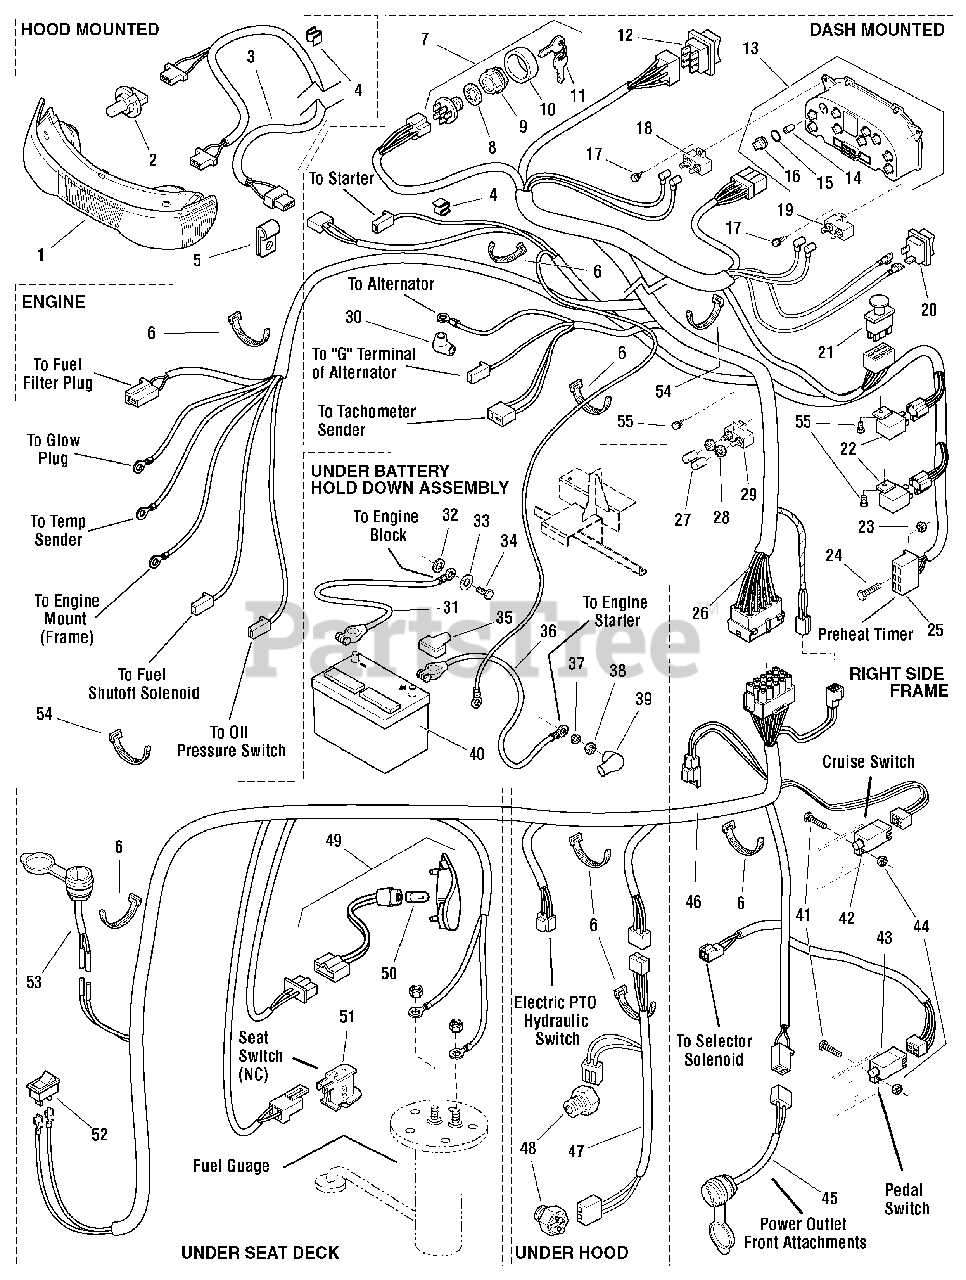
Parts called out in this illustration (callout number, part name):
2	BULB, Headlight, Halogen
3	HARNESS, Headlight
5	CLAMP, Wire 3/8 Diameter
6	TIE, Self Locking 7 in. Long
7	SWITCH ASSEMBLY, Ignition 5/8-32, 6 Pin INDAK
8	LOCKWASHER, Internal Tooth, 5/8, Thin
9	NUT, Hex Flange 5/8-32 Ignition Switch
10	COVER, Ignition Switch, Black
11	KEYS, Set of 2
12	SWITCH, Electric Lift, 6 Terminal
13	PANEL, Instrument
14	BULB, Instrument Panel
15	SEAL, Lamp Socket Plug
16	HOLDER, Bulb, Instrument Panel (Includes Ref. No. 15)
17	SCREW, Hex Washer Head, Thread Cutting, #12-24 x 5/8
18	BREAKER, Circuit 12VOLT 10AMP
19	BREAKER, Circuit 12VOLT 20AMP with Tab
20	SWITCH, Headlights, 2 Terminal
21	SWITCH, PTO Push/Pull, Yellow
22	RELAY, 12VOLT 5 Blade
23	NUT, Hex Lock 10-24 with Nylock Insert, NC3B
24	SCREW, Round Head Phillips #10-24 x 3/4
25	RELAY, Glow Plug
26	HARNESS, Main Diesel
27	COVER, Wire, Black, Vynil
28	NUT, Hex & Washer Assembly, KEPS
29	BREAKER, Circuit 30AMP 12VOLT
30	COVER, Terminal Red
31	CABLE, Battery, # 4 x 10 in Long, Black
32	LOCKWASHER, External Tooth 5/16
33	WASHER, 3/8
34	CAPSCREW, Hex Head M08-1.25 x 16MM
35	INSULATOR, Battery Terminal, Red
36	CABLE, Battery, # 4 x 15 in Long, Red
37	LOCKWASHER, Spring 5/16
38	NUT, Hex Flange M08-1.25
39	BOOT, Cable Terminal
40	BATTERY, 12VOLT 6CELL 500AMPS CCA
41	SCREW, Hew Washer Head Slot, #10-24 x 5/8
42	SWITCH, Push Button, Cuise Control
43	SWITCH, Push Button, Foot Pedal
44	NUT, Hex KEPS #10-24
45	HARNESS ASSEMBLY, Power Outlet
46	HARNESS, Rear
47	HARNESS, Trasnmission, PTO Lights (540 PTO Only)
48	SWITCH, Interlock Ball Check 5/16 (540 PTO Only)
49	TAIL LIGHT ASSEMBLY
50	BULB, Tail Light
51	SWITCH, Push Button, Operator Present
52	SWITCH, Rocker, Solenoid Select
53	OUTLET, 12 Volt
54	TIE, Self Locking 15 in. Long
55	FASTENER, Panel
